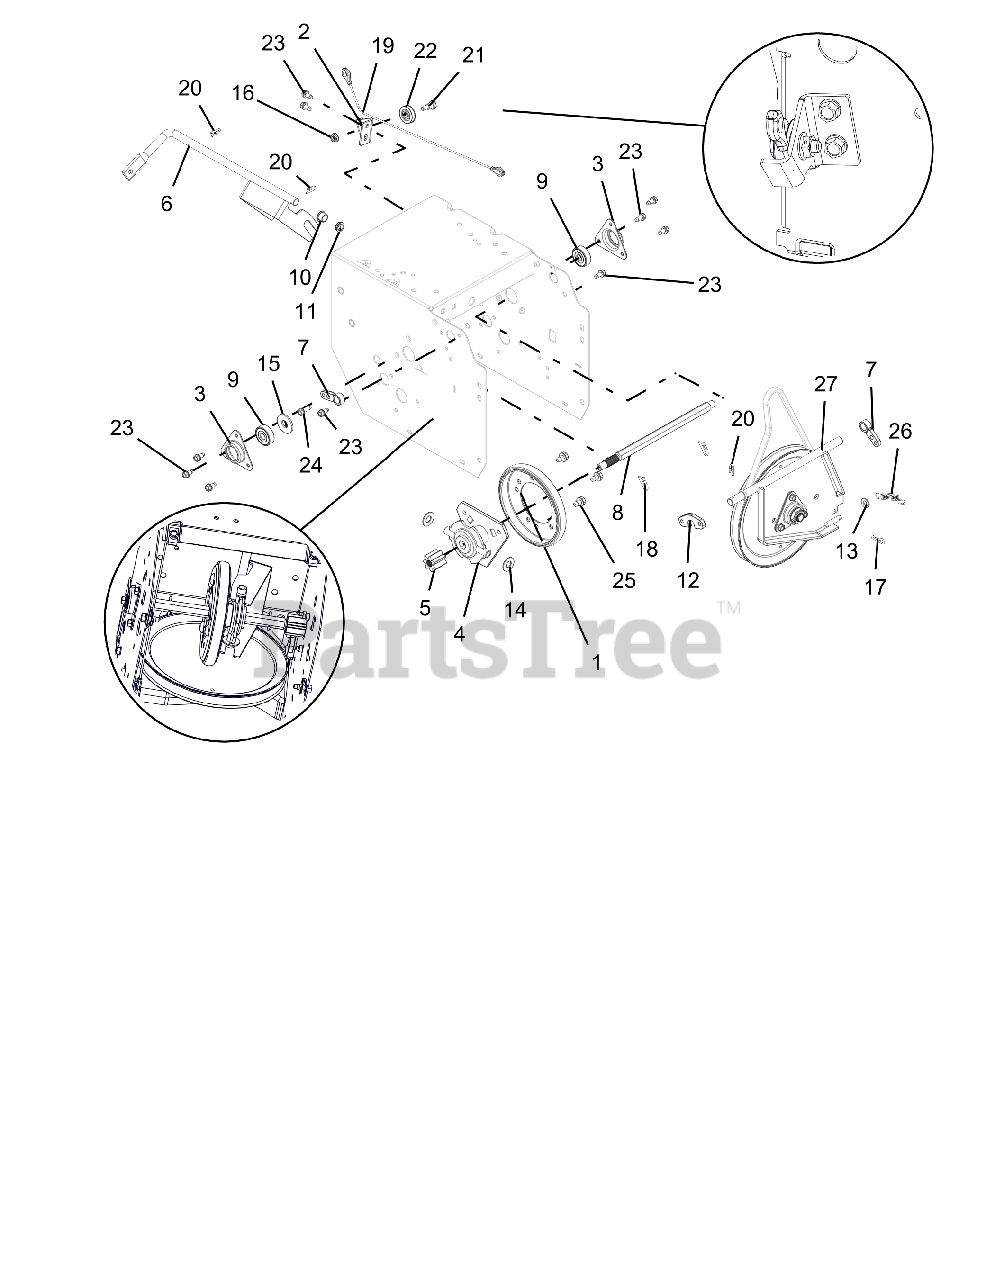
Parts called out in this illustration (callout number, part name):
1	FRICTION, DISC
2	BRACKET, CABLE PULLEY
3	FLANGE, BEARING
4	CARRIER, DRIVE DISK
5	GEAR, PINION, 7 TOOTH W/SPLINE
6	WELDMENT, SHIFT FORK
7	SUPPORT BUSHING, SWING GATE
8	SHAFT, HEX W/SPLINE
9	BRG-BALL .437X1.375X.437
10	BUSHING, POLYLINER-.50 SPLIT
11	BUSHING, POLYLINER-.50 SNAPIN
12	SPACER, SWING GATE
13	@WSHR-FL-STL.344X.688X.065YWZC
14	WSHR-FL-STL .505X1.00X.062YWZC
15	@WSHR-FL-STL.563X1.38X.109YWZC
16	@NUT-LK-CTR-FLG .25-20 YWZC
17	PIN-HAIR INT .08X.18X1.18 YWZC
18	PIN, SPRING CLIP
19	CABLE, LOWER TRACTION (CMPCT)
20	CLIP, SPRING
21	BOLT, SHLDR-.375X.375X.25-20
22	PULLEY, CABLE
23	SCR-TAP .25-20X.50 HWH TR YWZ
24	SCR-TAP-PM .25-20X.75 TR YWZ
25	@SCR-TAP .31-18X.50 HWH TR YWZ
26	SPRING, EXT. .043X.438X1.64
27	PLATE, SWING - ASSEMBLY
